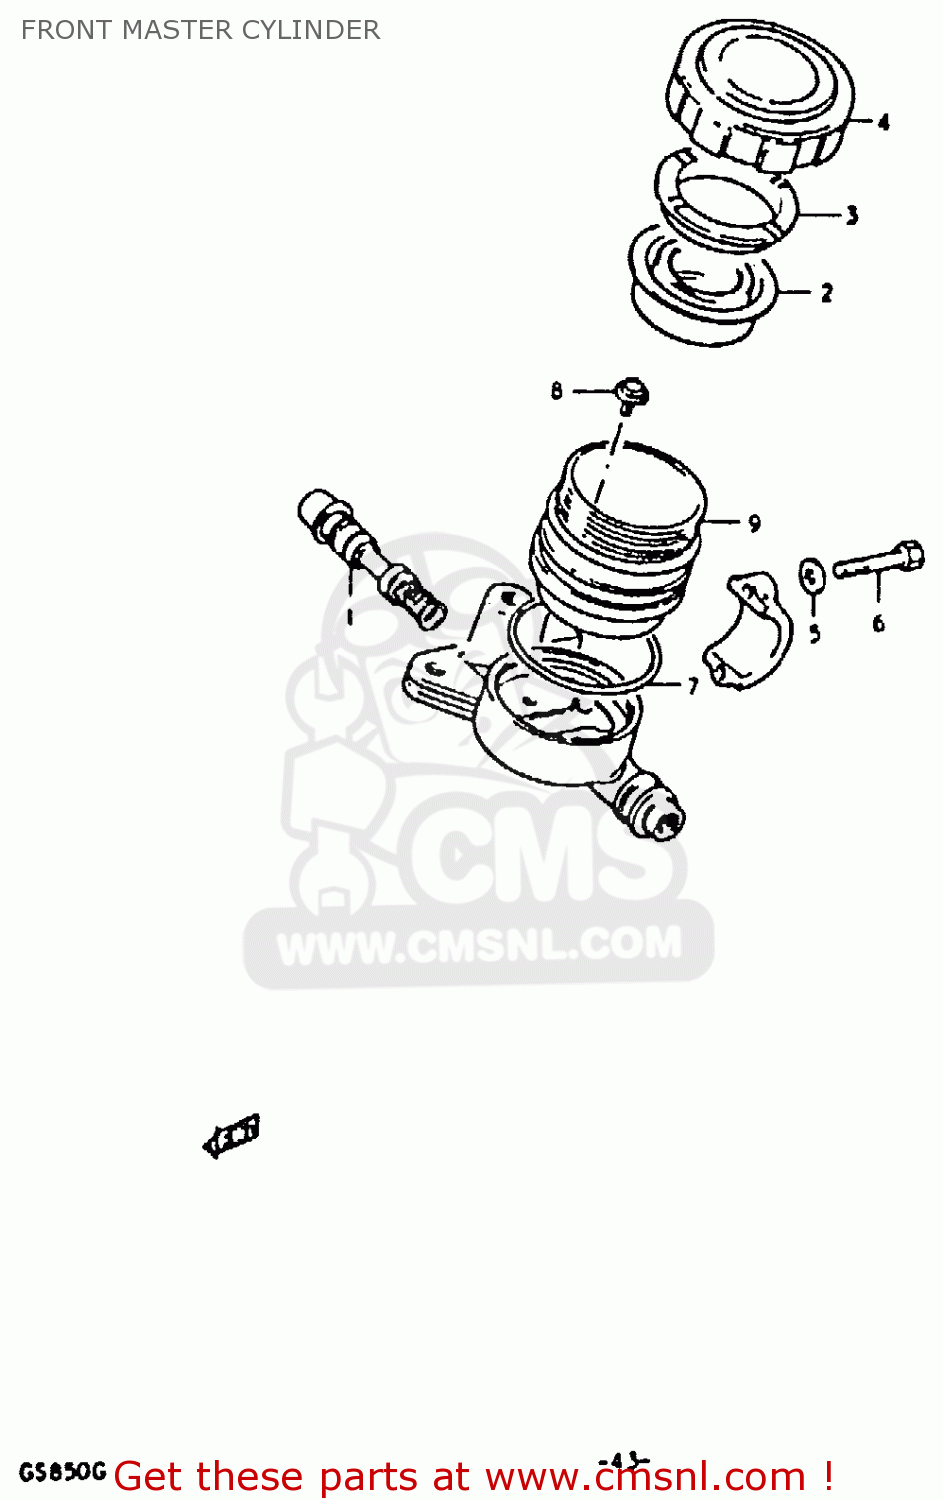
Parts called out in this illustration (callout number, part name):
1	CYLINDER ASSEMBLY,MASTER
2	DIAPHRAGM
3	PLATE,DIAPHRAGM
4	CAP
5	WASHER
6	BOLT
7	O RING
8	SCREW,MASTER CYLINDER
9	RESERVOIR
